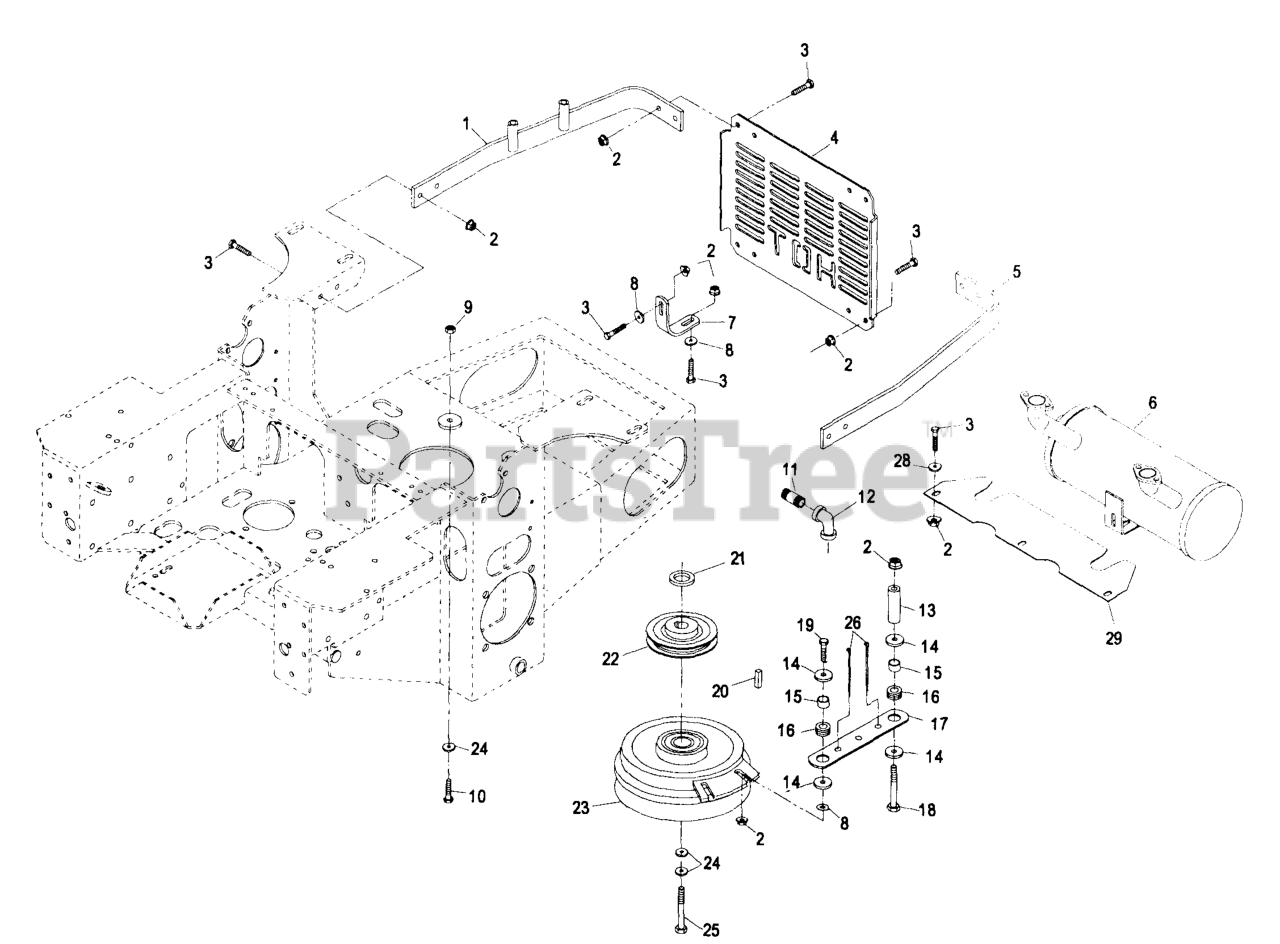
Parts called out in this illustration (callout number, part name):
1	STRAP-GUARD, ENGINE
4	Shield, Engine Guard
7	BRACKET-SUPPORT, MUFFLER
11	NIPPLE,PIPE
12	ELBOW-90 DEG
16	GROMMET
17	STRAP-CLUTCH, BRAKE
22	PULLEY
24	WASHER-SPRING
26	TIE-PLASTIC
27	WASHER-SPRING
